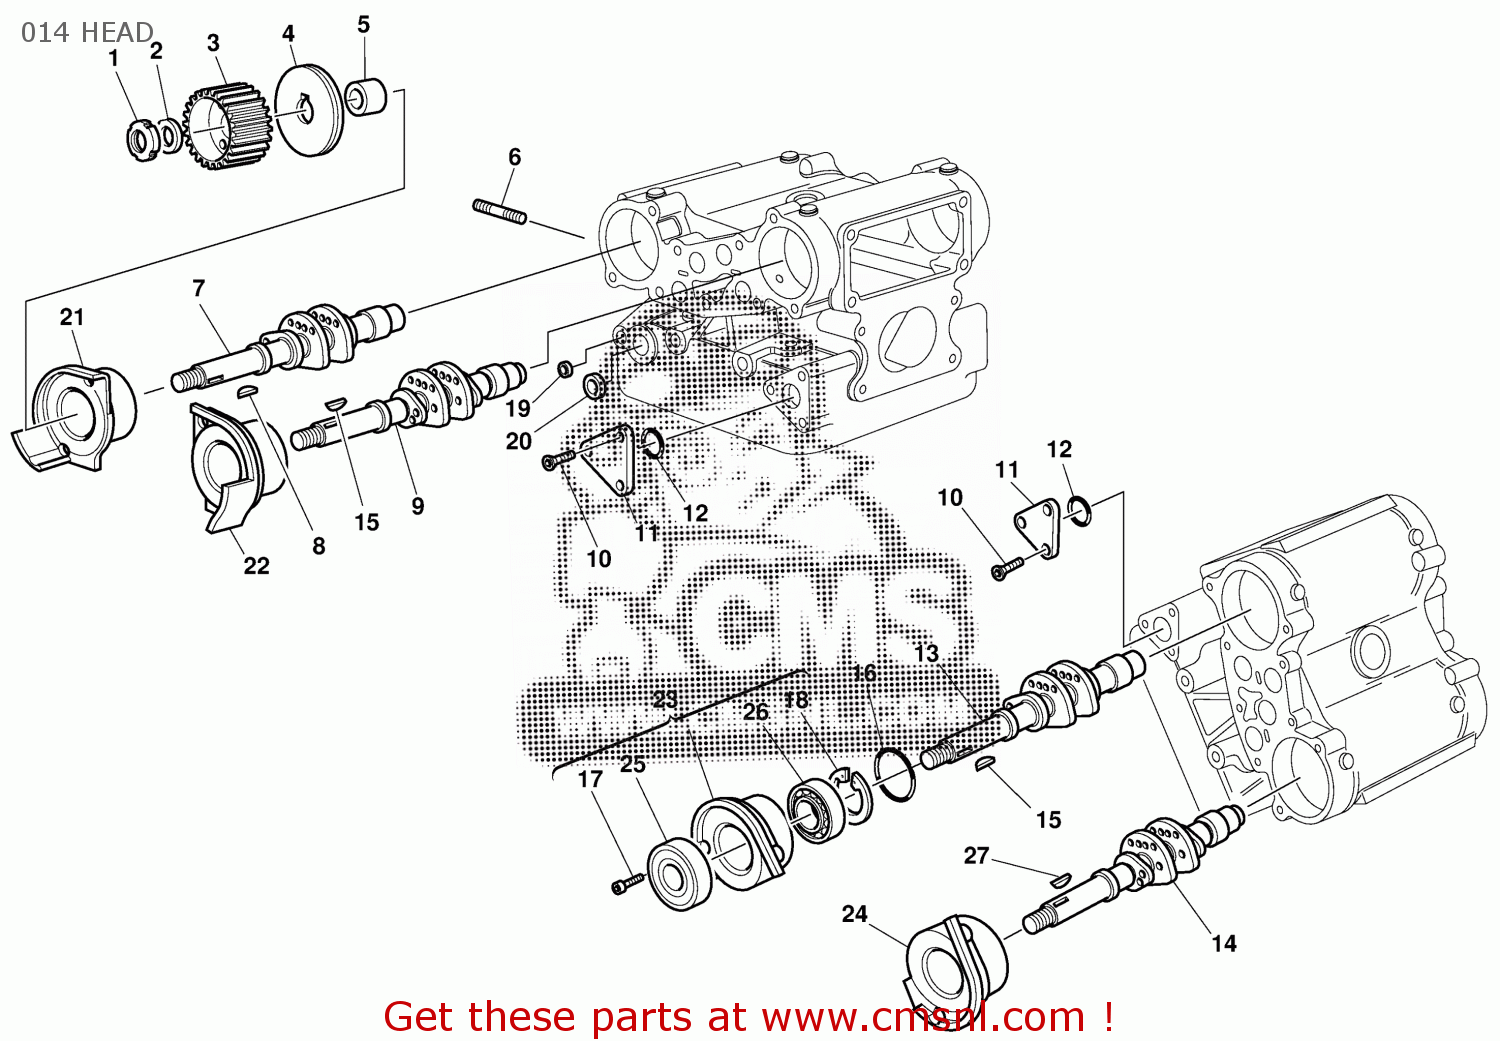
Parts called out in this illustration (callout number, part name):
1	ELASTIC-STOP RING NUT
2	WASHER 15.2X24X1
3	PULLEY, TIMING
4	THRUST WASHER 2 MM
5	PULLEY SPACER
6	STUD BOLT
7	VERTICAL EXHAUST CAMSHAFT
8	WOODRUFF KEY 4X5
9	VERTICAL INTAKE CAMSHAFT
10	SCREW
11	COVER
12	O-RING
13	HORIZONTAL INTAKE CAMSHAFT
14	HORIZONTAL EXHAUST CAMSHAFT
15	PLATE
16	O-RING
17	SCREW TCEI M6X1.00X16
18	CIRCLIP
19	PLUG
20	PLUG 16 MM
21	REAR COMPLETE CAP TIMING SIDE
22	FRONT COMPLETE CAP TIMING SIDE
23	REAR COMPLETE CAP
24	FRONT COMPLETE CAP
25	SEAL RING ANGUS 22MM
26	BALL BEARING 6203
27	WOODRUFF KEY 6
